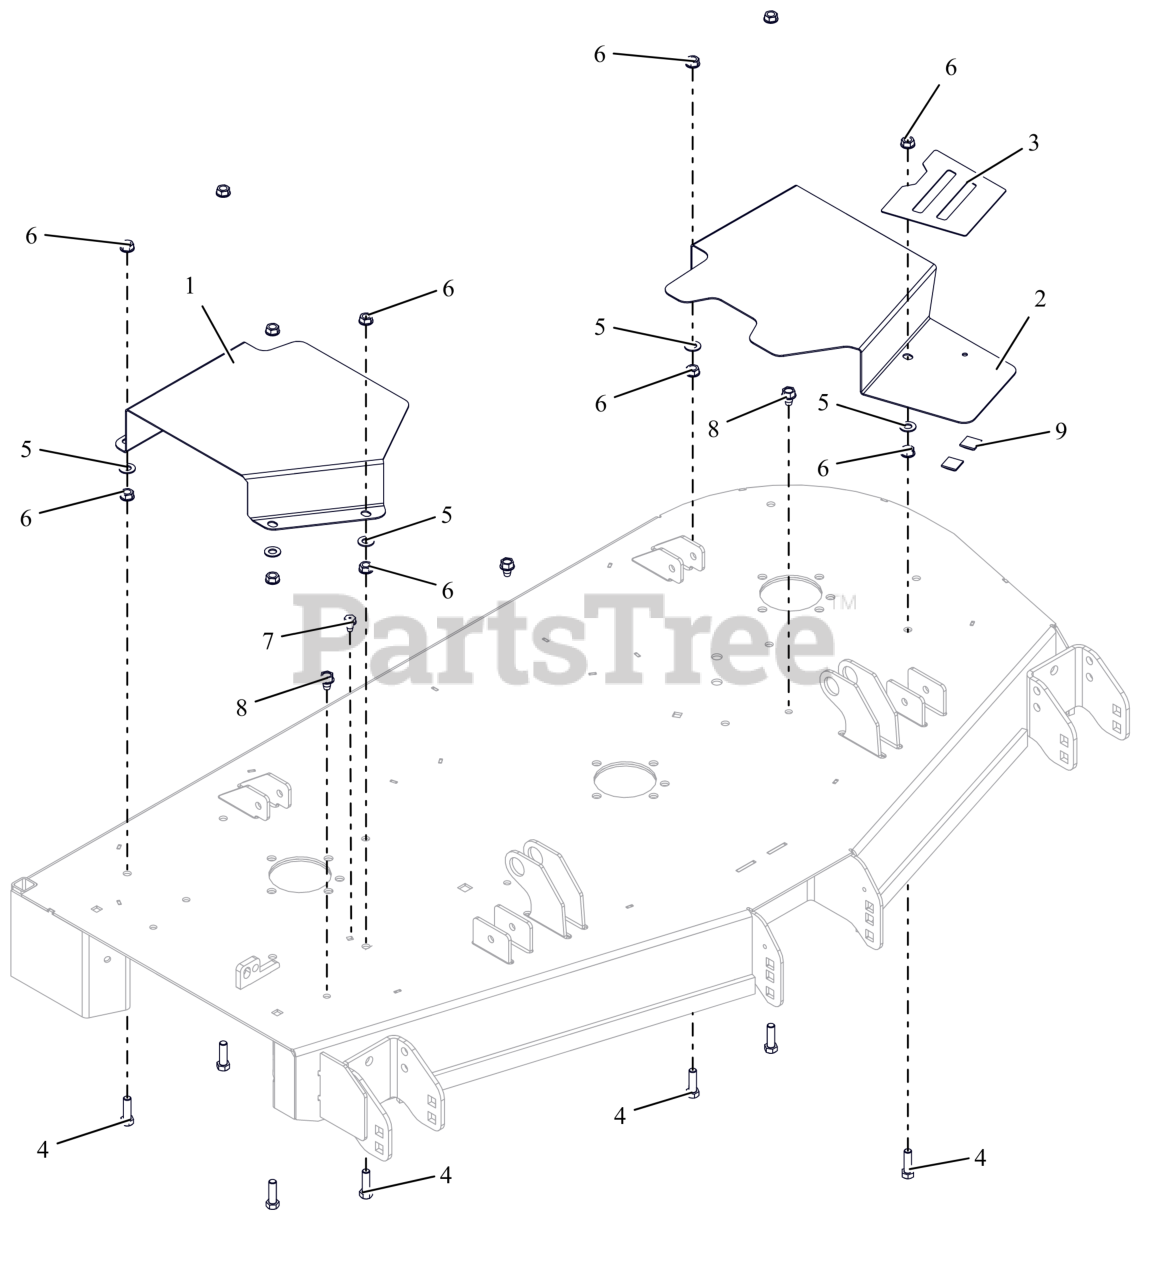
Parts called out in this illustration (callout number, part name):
1	COVER, BELT 52" & 60" RIGHT
2	COVER, BELT 52" LEFT
3	GRIP, TAPE 52-60 BELT COVER
4	BLT, HEX .38-16X1.25 G5 ZCC
5	WSHR,FLT .406X.812X.065 ZCC
6	NUT, SPNLK-FLG .38-16 G5 ZCC
7	SCR,TAP .312-18X.50 HWH TR ZCC
8	SCR,TAP .375-16X.50 HWH TR ZCC
